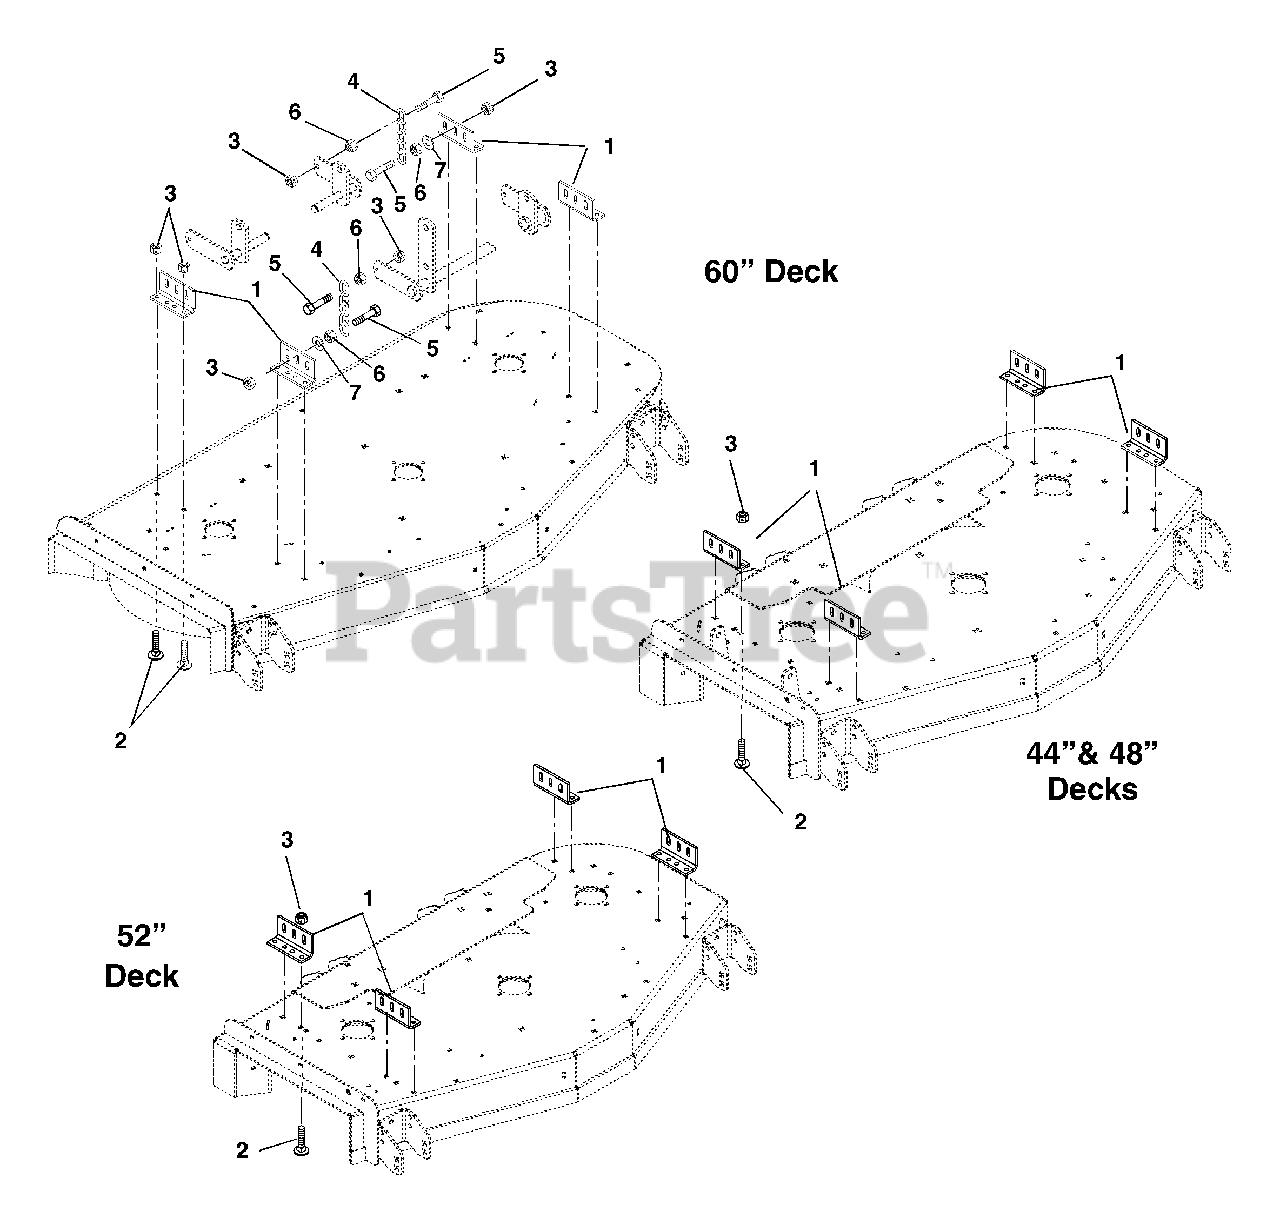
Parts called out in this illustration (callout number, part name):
1	Bracket, Mower Mounting
2	Bolt-Round Head Square Neck .38-16 x 1.00 Grade 2
3	Nut-Locking-Top-Flange .38-16
4	Chain, Link
5	Bolt-Hex .38-16 x 1.50 Grade 5
6	Nut-Hex .38-16
7	Washer-Flat-Steel .406 x .812 x .065
